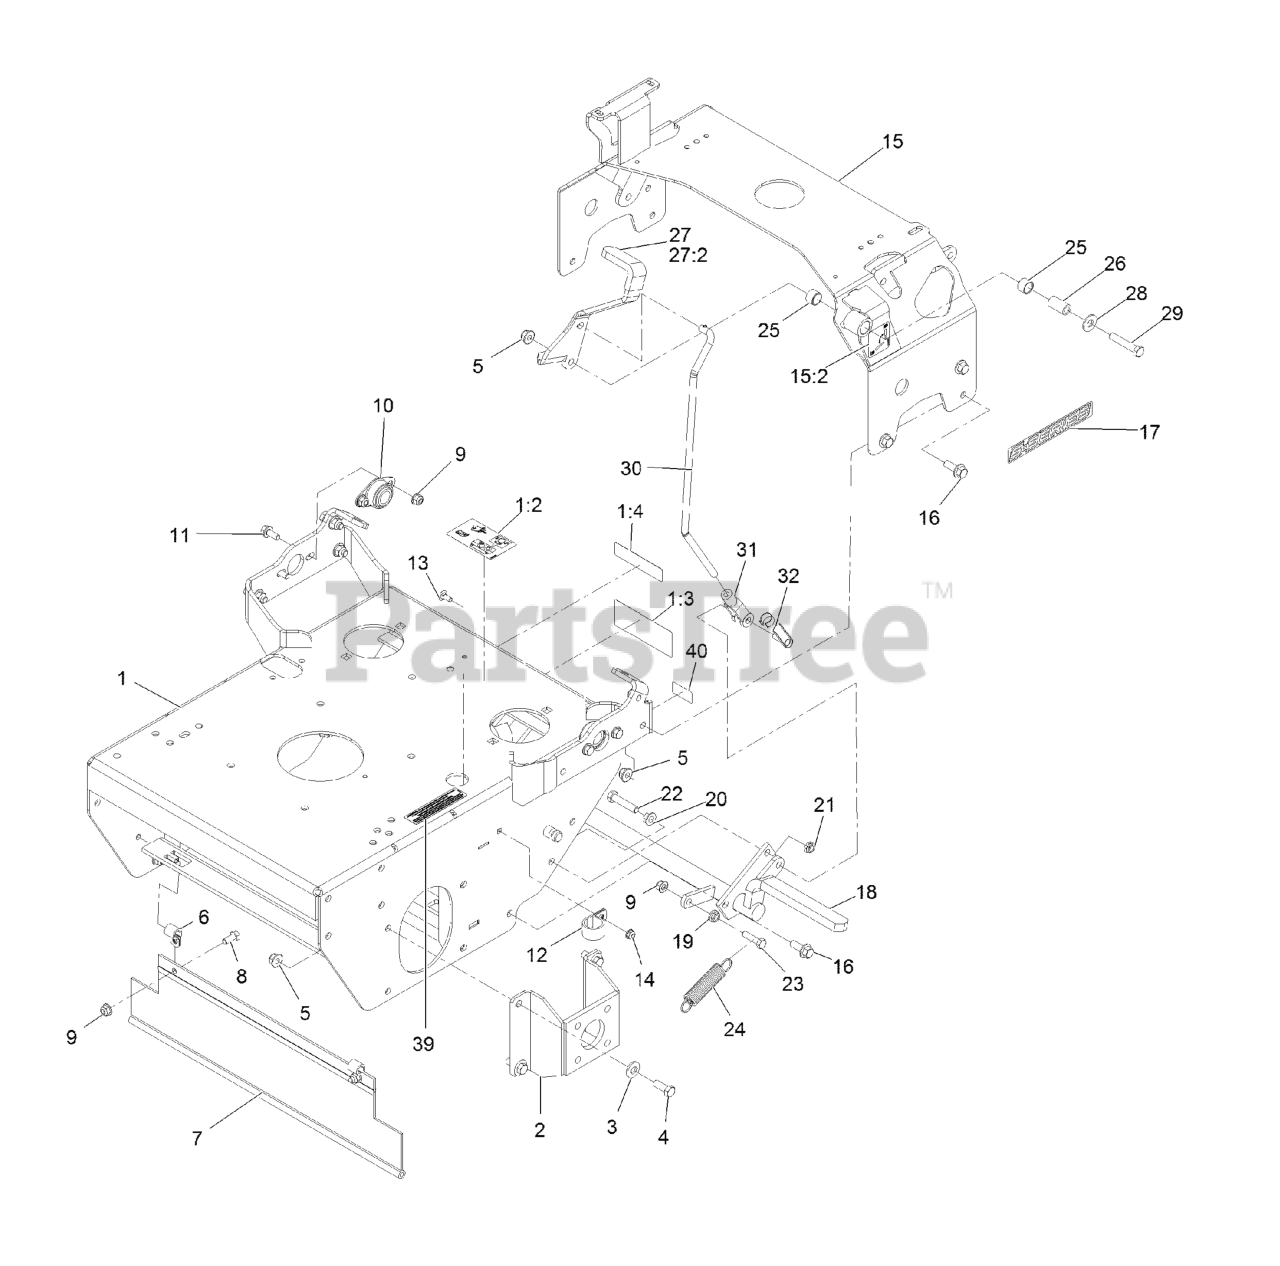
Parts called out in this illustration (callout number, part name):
1	ASM, ENGINE DECK W/ DECAL
1:2	DECAL-DRIVE RELEASE
1:3	DECAL-WARNING, SULKY
1:4	DECAL-WARNING
2	WLD,MOTOR MOUNT 48&52
3	WASHER-BELLEVILLE
4	SCREW-HH
5	NUT-HF, NI
6	CLIP-LOOM
7	SHIELD-DRAG
8	SCREW-HH
9	NUT-HF, NI
10	BEARING-FLANGE, SIDE
11	SCREW-HHF
12	CLIP-LOOM
13	SCREW-CARR
15	ASM, TANK SUPPORT W/ DECA
15:2	DECAL-PARK BRAKE, CE
16	SCREW-HHF 3/8-16 X 1
17	DECAL-S-SERIES
20	NUT-HHF, WHIZ
22	SCREW-HH
23	SCREW-HH
24	SPRING-IDLER
25	SLEEVE-BUSHING
26	BUSHING-PIVOT
27	ASM, BRAKE LEVER W/ GRIP
27:2	GRIP-LEVER
28	WASHER-FLAT
29	SCREW-HH
30	LINKAGE, BRAKE
31	YOKE-LINKAGE, BRAKE
32	PIN-SPRING, CLEVIS
39	DECAL-ARRESTOR, SPARK
40	Decal-Patent Ttco.Com
